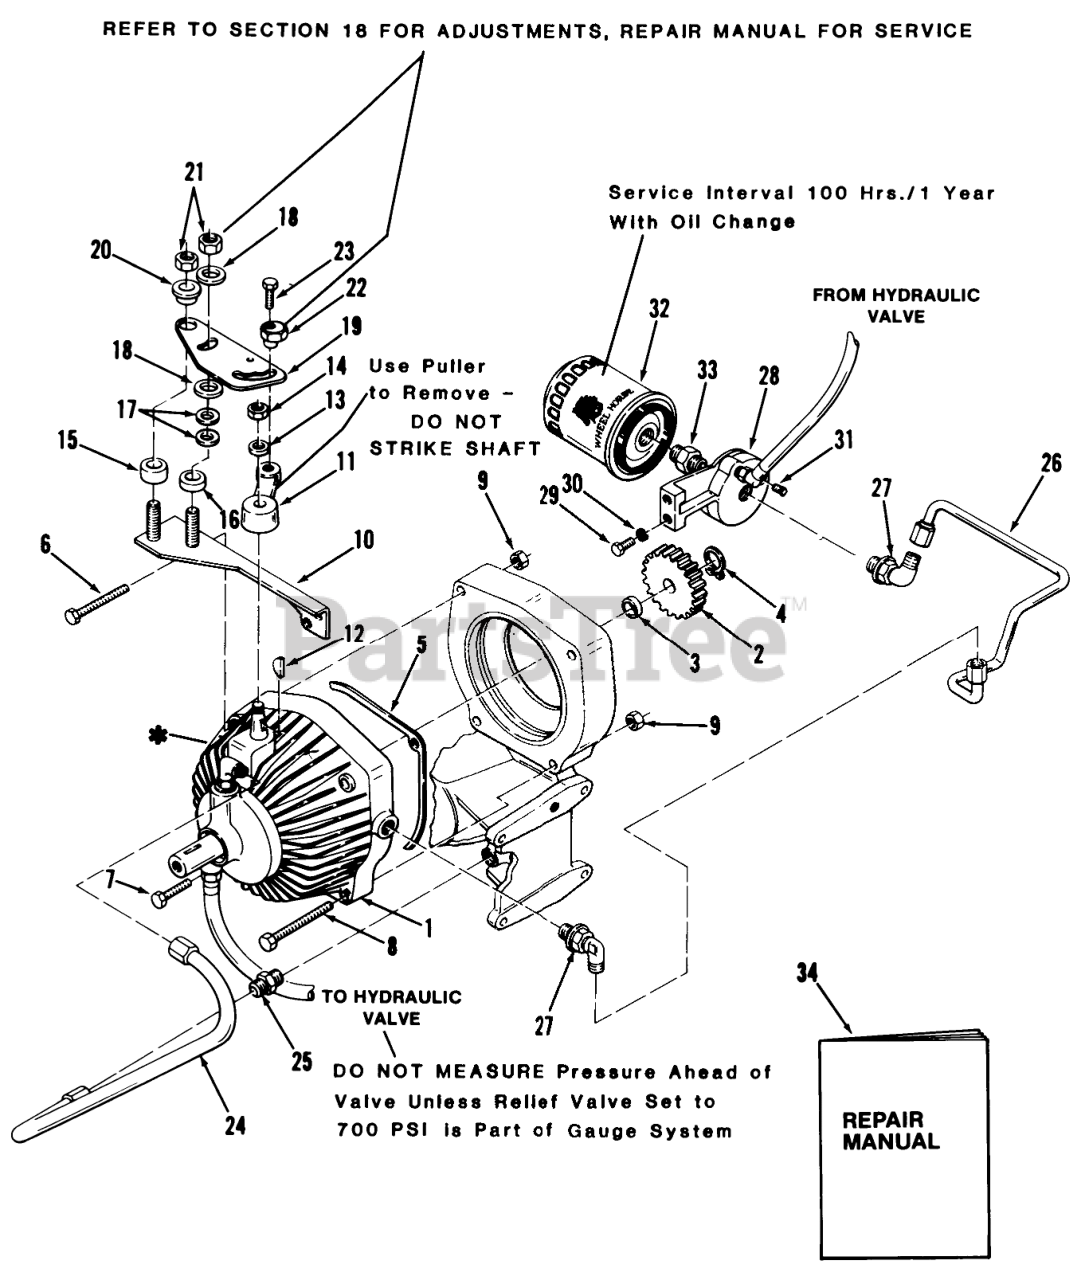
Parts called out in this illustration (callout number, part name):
1	Pump & Motor
2	GEAR 22T DRIVE
3	SPACER GEAR
4	SNAP RING- 5/8 EXT
5	GASKET
6	H H C S
7	Bolt
8	Bolt 3/8-16 x 6 1/2
9	Nut
10	ASSY-PLATE B
11	ARM-SPEED CONTROLB
12	Key #5 Woodruff
13	Washer
14	Eslok Nut
15	SPACER-PIVOT
16	SPACER-FRICTION
17	WASHER-SPRING DISC
18	FRICTION WASHER
19	CAM-SPEED CONTROL (NS)
20	CAM-SPACER
23	Bolt
24	ASSY-TUBE-SUCTION
25	FITTING-TUBE
26	ASM-TUBE FILTER OUTL
27	ELBOW
28	BASE-FILTER
29	Bolt
30	Lockwasher
31	PLUG 1/4 PIPE ALLEN
32	Filter-Oil
33	FITTING
34	Repair Manual
